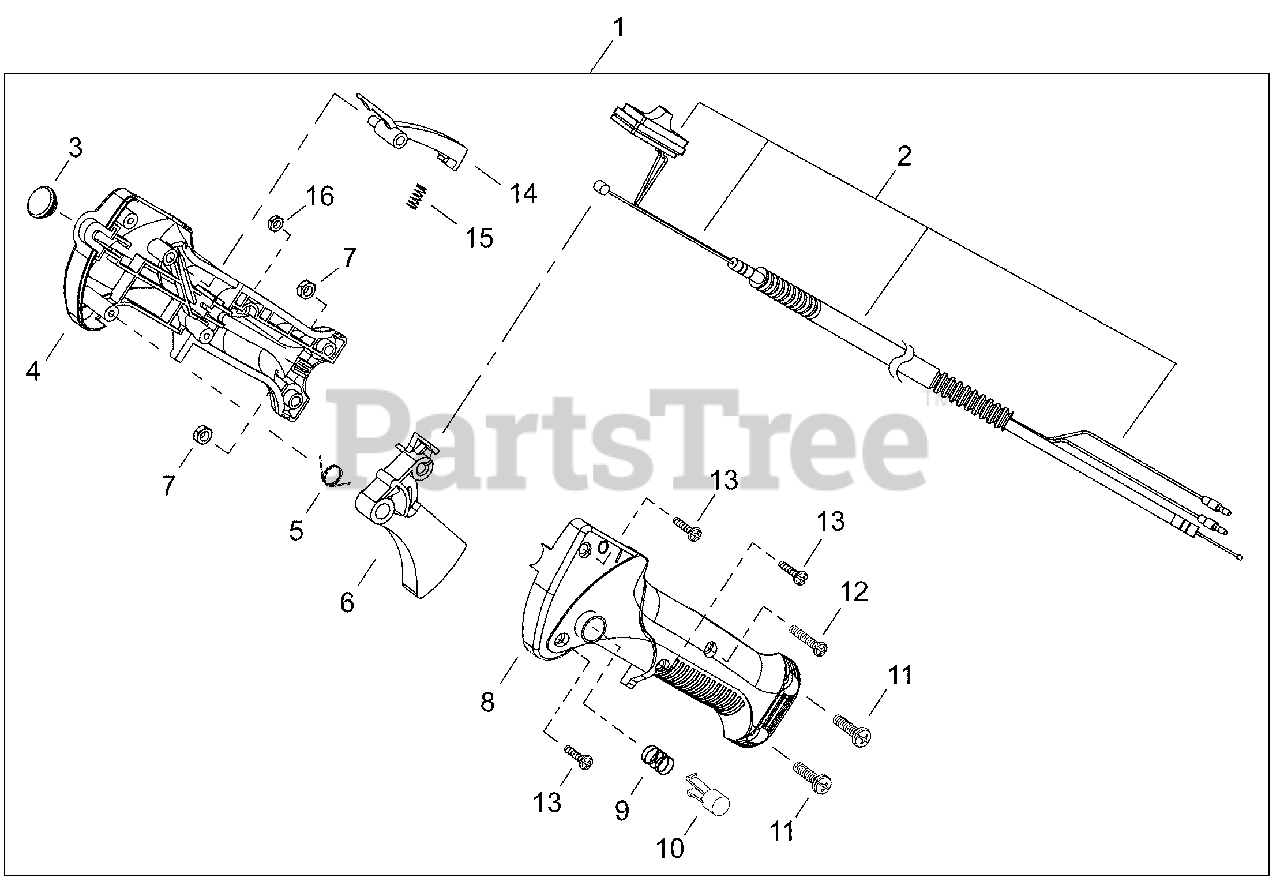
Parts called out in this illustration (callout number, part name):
1	THROTTLE CONTROL ASSY
2	THROTTLE CONTROL ASSY
3	PLUG
4	HANDLE, CONTROL - RIGHT
5	SPRING
6	TRIGGER, THROTTLE
7	NUT - 5
8	HANDLE, CONTROL - LEFT
9	SPRING
10	BUTTON, THROTTLE LOCK
11	SCREW - 5X20
12	SCREW - 4X23
13	SCREW - 4X16 -- TAPPING
14	LEVER, TRIGGER LOCKOUT
15	SPRING
16	NUT - 4
